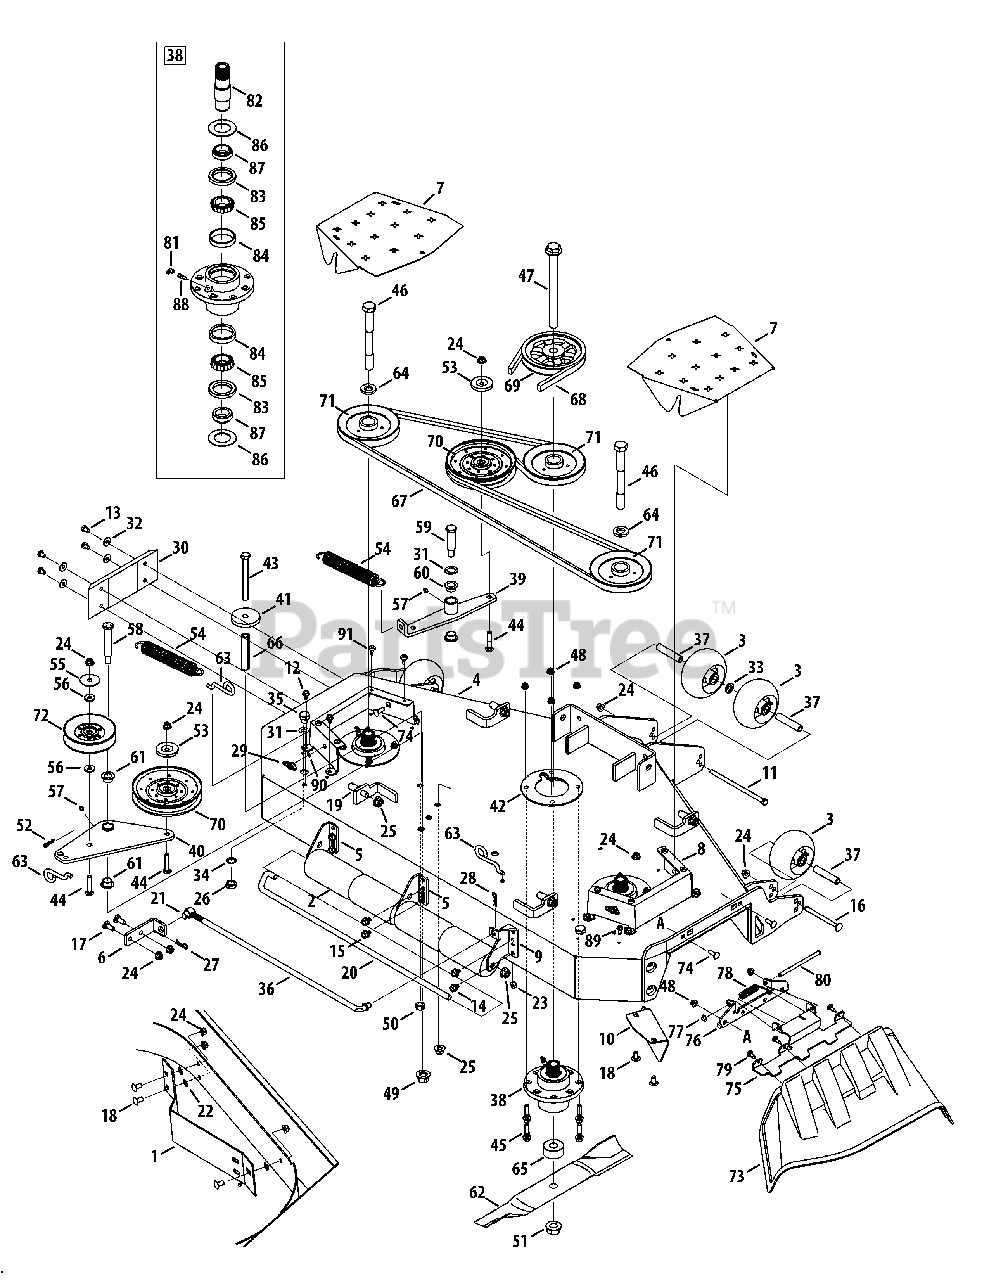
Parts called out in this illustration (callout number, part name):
1	Baffle, 54" Adjustment
2	Anti-Scalp Roller Assembly
3	Complete Wheel, 5.00 Dia.
4	54" Deck
5	Rear Roller Mount Bracket
6	Deck Stabilizer Mount Bracket
7	Deck Belt Cover
8	Deck Belt Cover Bracket
9	Rear Roller Bracket, RH
10	Chute Baffle
11	Hex Cap Screw, 3/8-16 x 7.25
12	Screw, 5/16-18 x .500
13	Screw, 5/16-18 x .500
14	Screw, 3/8-16 x .750
15	Screw, 3/8-16 x .500
16	Carriage Screw, 3/8-16 x 4.50
17	Carriage Bolt, 3/8-16 x 1.00
18	Carriage Bolt, 3/8-16 x .750
19	Pin, 1/2-13 x .625 x 1.2
20	J-Hook w/ Threaded Roller
22	Push Nut, 3/8
23	Jam Lock Nut, 3/8-16
24	Nut, 3/8-16, Flangelock
25	Nut, 1/2-13, Flangelock
26	Hex Nut, M16-1.5
27	Click Pin, .092 x 1.64
28	Internal Cotter Pin
30	Skid Guard Plate
31	Washer, .793 x 1.24 x .06
32	Flat Washer, .343 x .880 x .062
33	Flat Washer, .632 x 1.00 x .160
34	Lock Washer, 17 x 23.8 x 1.95
35	Plug, Screw, M16-1.5
36	Deck Support Rod, 1/2" Dia.
37	Wheel Spacer
38	Spindle Assembly
39	Deck Idler Arm
40	Idler Assembly
41	Spacer, .5375 x 2.75 x .375
42	Spindle Support Plate
43	Hex Cap Screw, 1/2-13 x 5.00
44	Screw, 3/8-16 x 2.00
45	Bolt, 5/16-18 x 1.25
46	Hex Cap Screw, 3/4-16 x 7.00
47	Hex Cap Screw, 3/4-16 x 9.00
48	Nut, 5/16-18, Flangelock
49	Nut, 5/8-18, Flangelock
50	Nut, 1/2-13, Hexlock
51	Nut, 3/4-16, Flangelock
52	Bow Tie Cotter Pin
53	Pulley Cap
54	Extension Spring, 1.248 x 8.5
55	Washer, .406 x 1.92 x .060
56	Washer, .406 x 1.00 x .105
57	Grease Fitting
58	Shoulder Bolt, 1.0 x 3.15, 5/8-18
59	Shoulder Bolt, .750 x 2.23, 1/2-13
60	Flange Bearing, .75 x .52
61	Flange Bearing, 1.00 x .75
62	Hi-Lift Blade, 19.0
63	Spring Rod Hook
64	Spacer, .812 x .218
65	Spacer, .760 x 2.00 x .925
66	Spacer, .405 x .75 x 3.875
69	Pulley, 6.96 OD x .750 ID
70	Idler Pulley
71	Spindle Pulley
72	Idler Pulley
73	Discharge Chute Assembly
74	Carriage Bolt, 5/16-18 x 1.00
77	Push Cap
78	Torsion Spring
79	Shoulder Screw, 1/4-20
80	Chute Rod
81	Grease Fitting, 45 degree, 1/4-28
82	Spindle Shaft
83	Seal, Oil
84	Cup Bearing
85	Cone Bearing
86	Washer, 1.50 x 2.52 x .075
87	Ring, Seal
88	Straight Adapter Fitting
89	Hex Flange Screw, 1/4-20 x .500
90	Speed Nut, .3125
91	Bumper, .62 Dia. x .3
